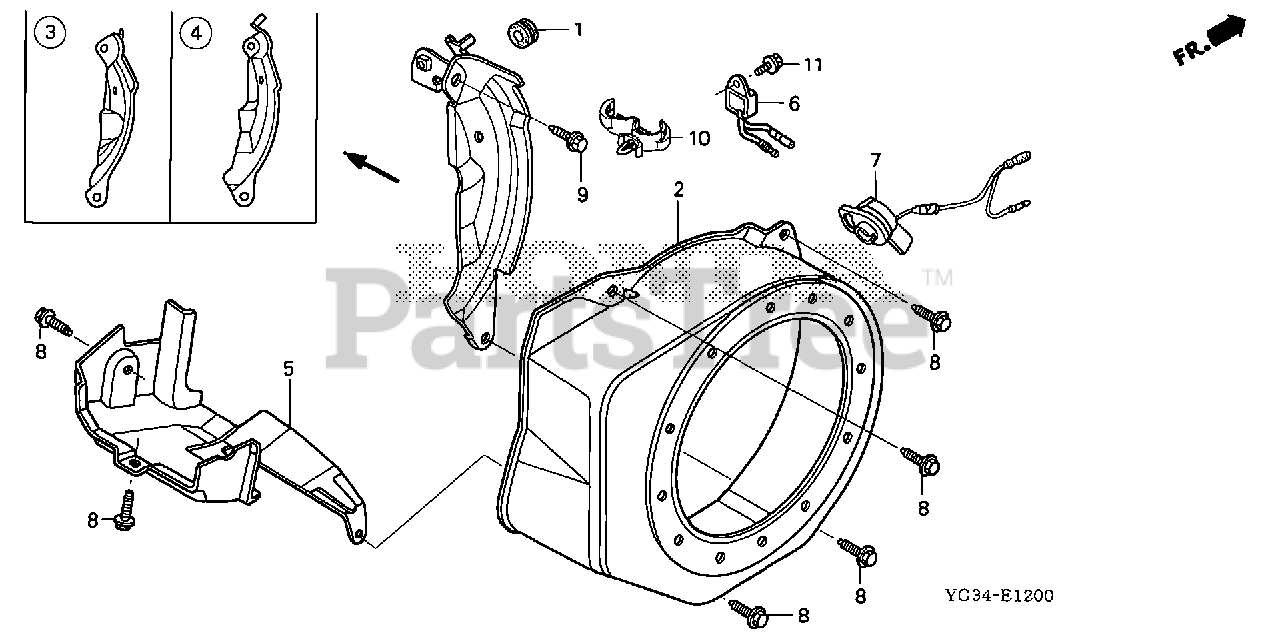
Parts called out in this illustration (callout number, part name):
1	GROMMET, ADJUSTING COVER
2	COVER, FAN *R280* (POWER RED)
3	PLATE, SIDE (OIL ALERT)
6	ALERT UNIT, OIL
7	SWITCH ASSY., ENGINE STOP (TOYO DENSO)
7	SWITCH ASSY., ENGINE STOP (MINDA)
8	BOLT, FLANGE (6X12) (CT200)
9	BOLT, FLANGE (6X20) (CT200)
10	CLIP, HARNESS
11	BOLT, FLANGE (6X8)
